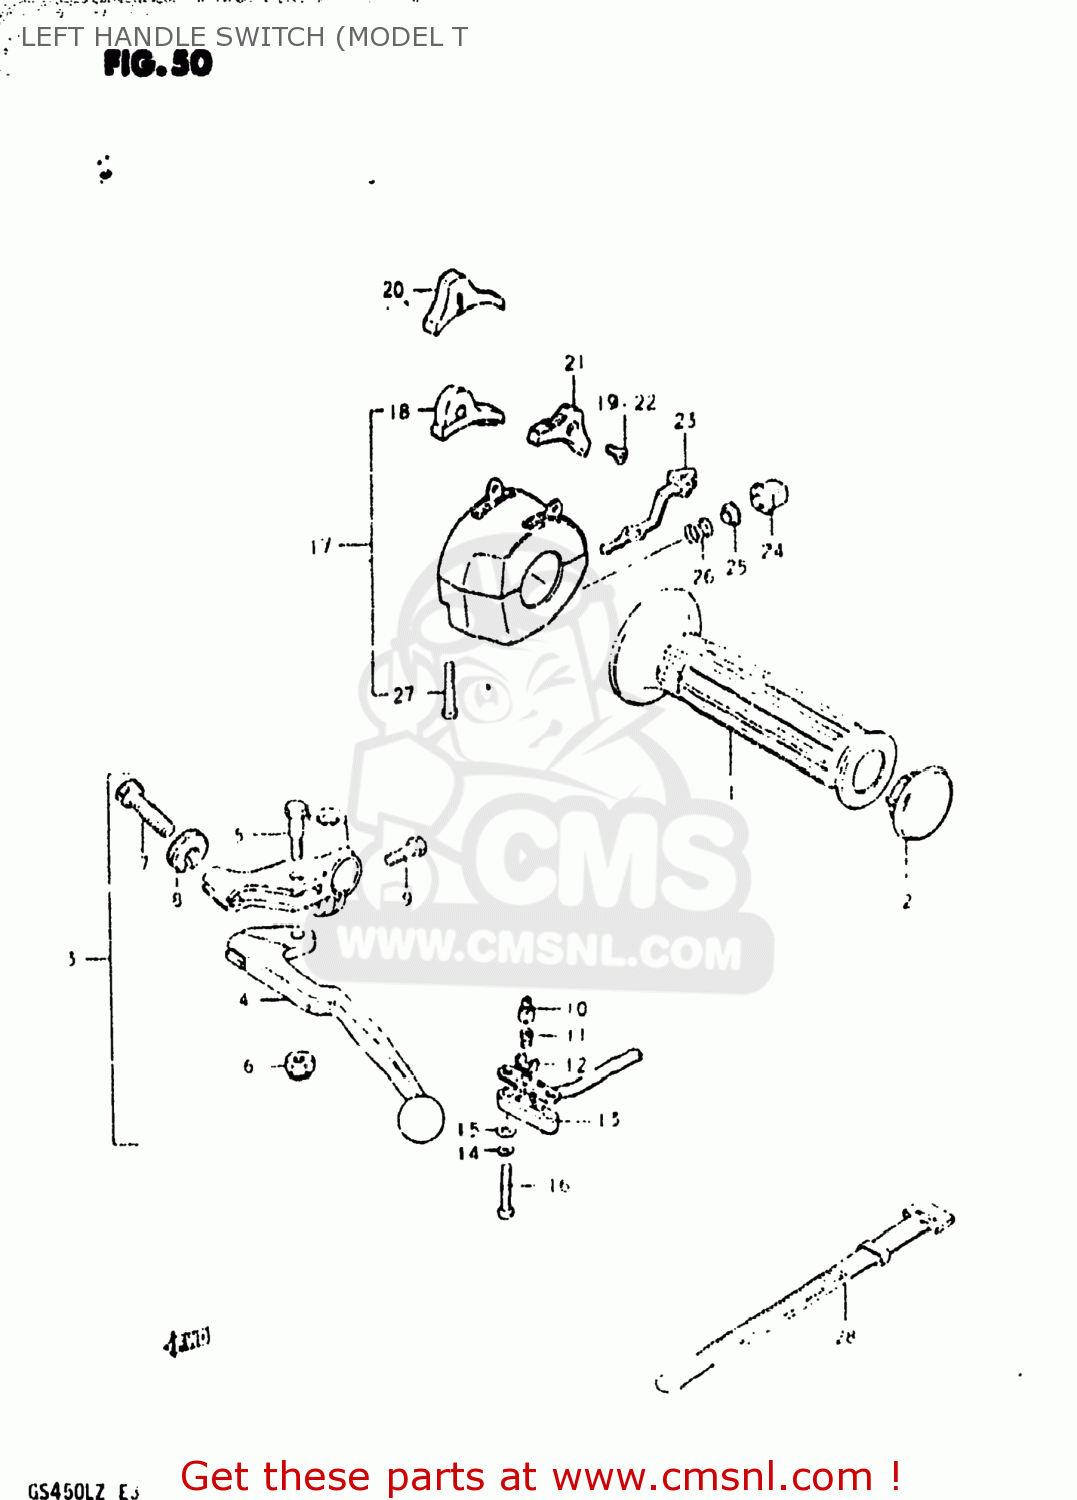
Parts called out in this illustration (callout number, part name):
1	GRIP,LEFT
2	CAP,GRIP END
3	LEVER ASSEMBLY
4	LEVER,CLUTCH
5	BOLT,LEVER
6	NUT 6MM
7	ADJUSTER,CABLE
8	NUT,CABLE ADJUSTER
9	BOLT,CLUTCH LEVER HOLDER
10	HOLDER
11	SPRING
12	PLATE
13	COVER,FR BK TERMINAL BASE
14	LOCK WASHER
15	WASHER
16	SCREW
17	SWITCH ASSY,HANDLE,L
18	KNOB,STOP
19	SCREW
20	KNOB,LIGHTING SWITCH
21	KNOB,DIMMER SWITCH
22	SCREW
23	KNOB,TURNSIGNAL
24	BUTTON,HORN
25	CONTACT
26	SPRING
27	SCREW
28	CLAMP(L:120)
